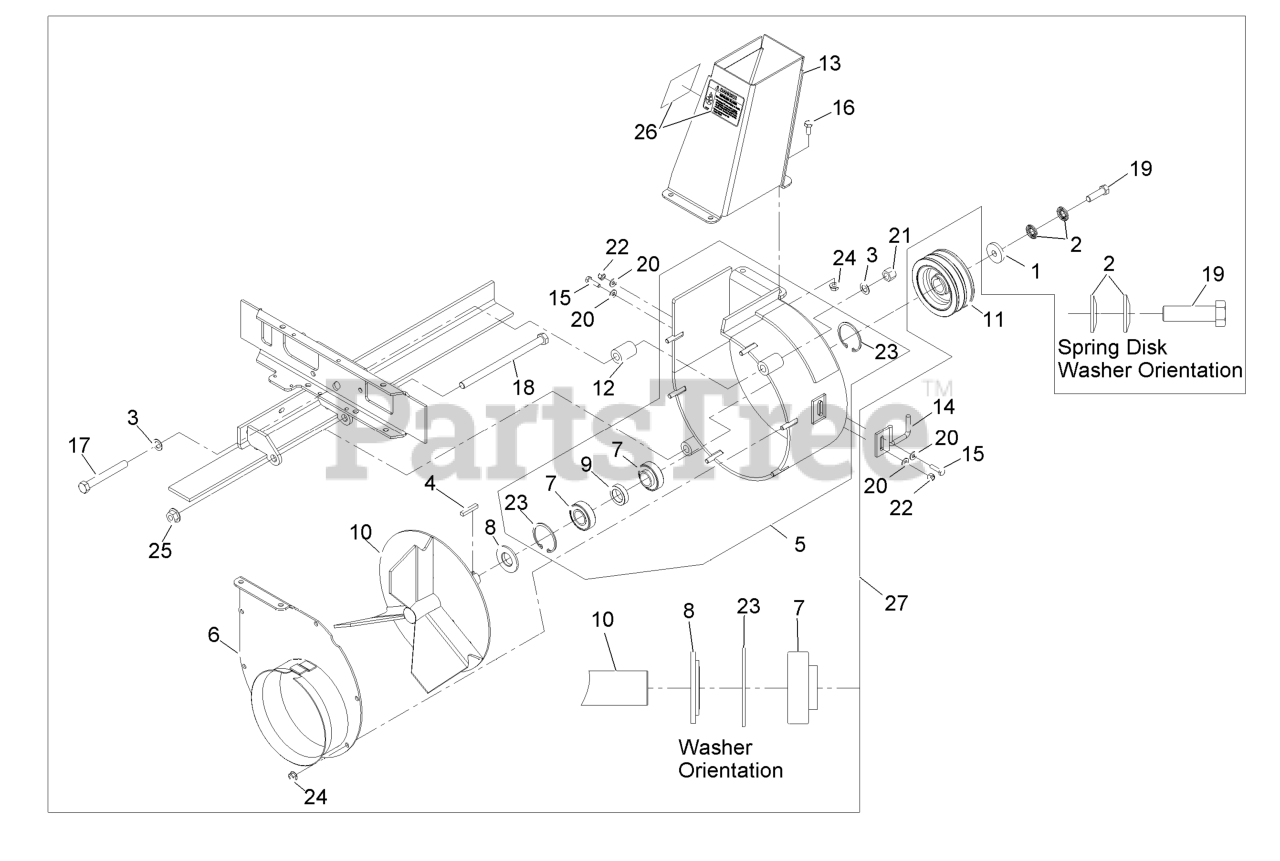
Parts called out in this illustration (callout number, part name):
1	WASHER-CLUTCH
2	WASHER-SPRING
3	WASHER-THRUST
4	KEY-SQUARE
5	ASM,HOUSING W/BEARINGS
6	COVER-BLOWER
7	BEARING-BALL
8	SPACER-BLOWER
9	SPACER-BEARING
10	IMPELLER-3 BLADE
12	SPACER-MOUNT
13	DISCHARGE CHUTE ASM
15	SCREW-HH
16	SCREW-HH
17	SCREW-HH
18	SCREW-HH
19	SCREW-HH
20	WASHER-FLAT
21	NUT-LOCK, NI
22	NUT-LOCK, NI
23	RING-SNAP
25	NUT-HHF
26	DECAL-DANGER IMPELLER
27	ASM,BLOWER COMPLETE
